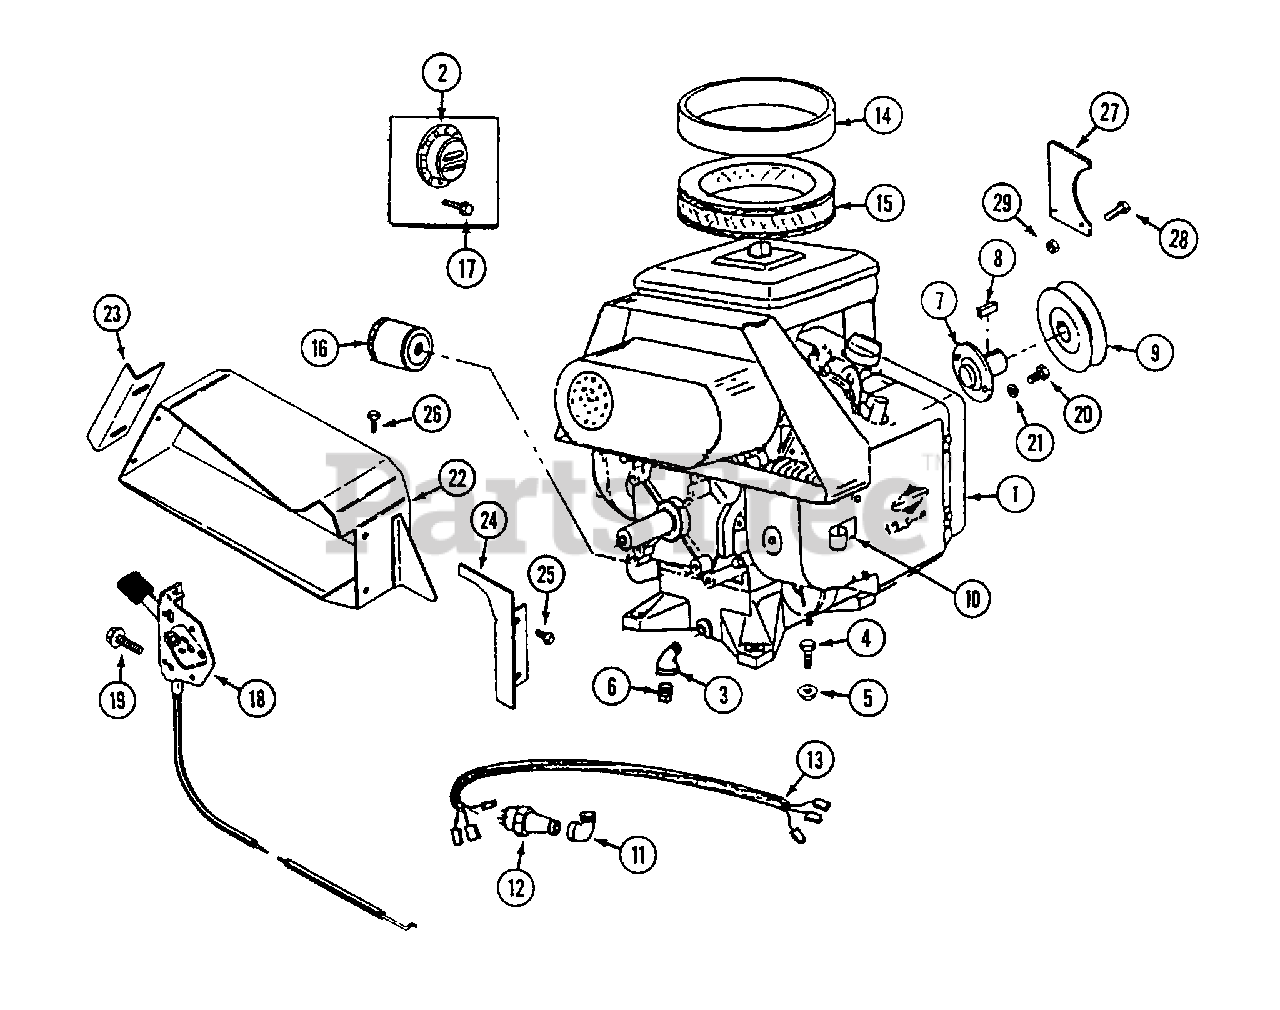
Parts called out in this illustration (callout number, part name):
1	ENGINE - B&S
2	DEFLECTOR - exhaust
3	ELBOW - street 3/8"
4	BOLT - 5/16" - 18 x 1-1/4"
5	NUT - 5/16" - 18
6	PLUG - pipe 3/8"
8	KEY - 1/4" x 1/4" x 1"
9	PULLEY - drive
10	RETAINER - starter cable
11	ELBOW - street 1/8"
12	UNIT - oil sending
13	HARNESS - wire
14	PRECLEANER
15	FILTER - air
16	FILTER - oil
17	SCREW - #8 - 32 x 3/8"
18	CABLE - choke
19	SCREW - #12 x 1/2"
20	LOCKWASHER - 3/8"
21	BOLT - 3/8" - 16 x 1"
22	DEFLECTOR - air
23	EXTENSION - front
24	EXTENSION - rear
25	SCREW - #8 - 18 x 3/8"
26	BOLT - 1/4" - 20 flange lock
27	RETAINER - belt
28	BOLT - 1/4" - 20 x 1"
29	NUT - 1/4" - 20 lock
